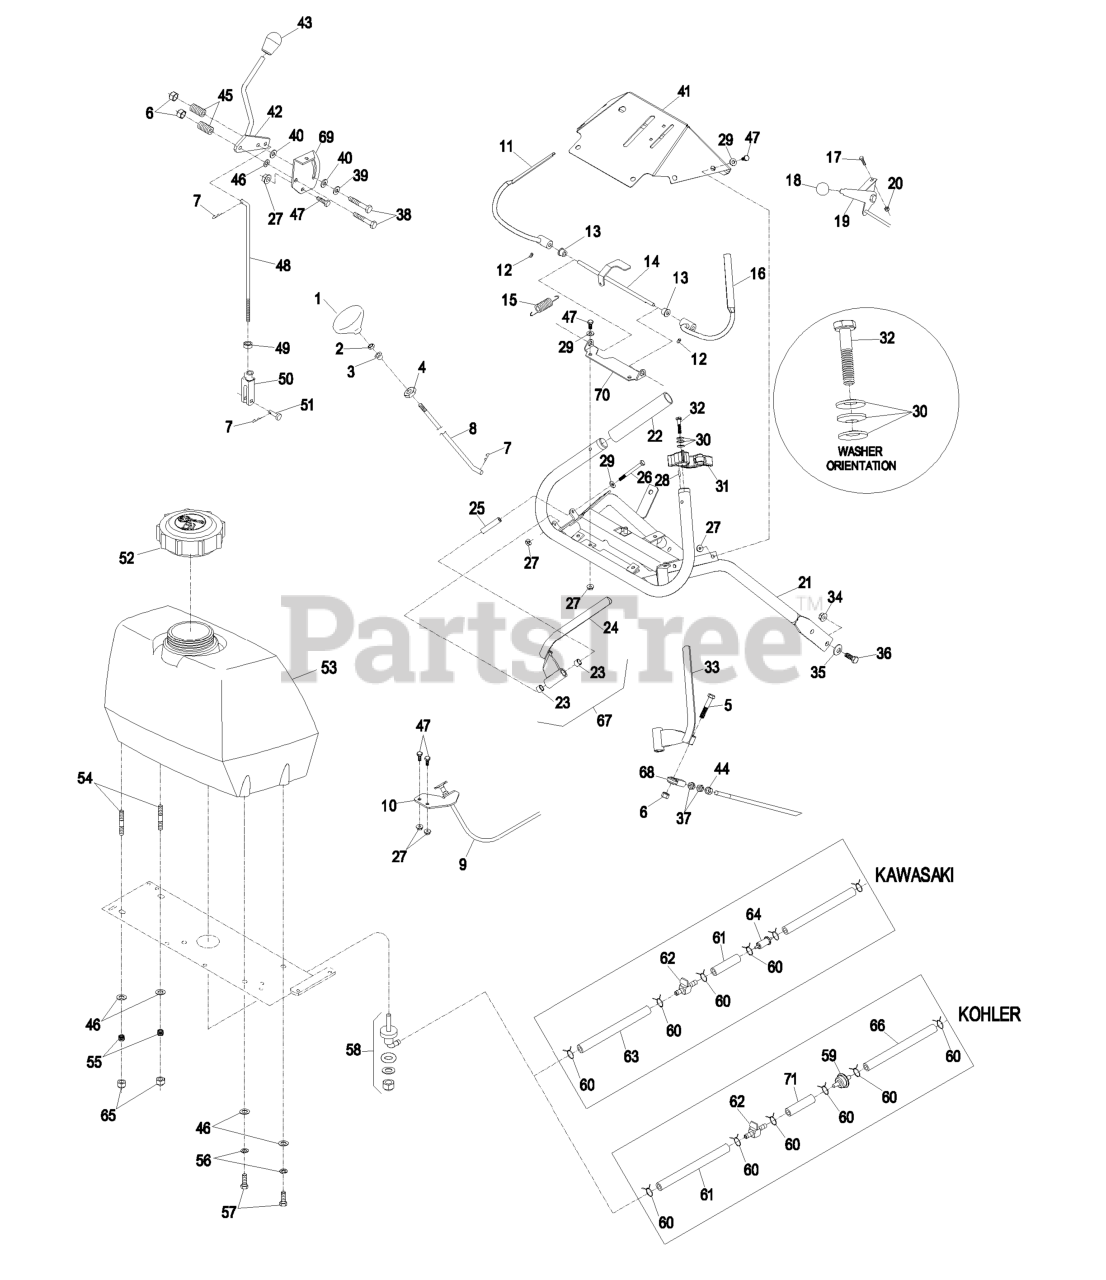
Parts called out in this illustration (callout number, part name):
1	KNOB-PUSH / PULL
2	NUT-JAM
3	BEARING-NYLON
4	NUT-PUSH
5	SCREW-HH
6	NUT-LOCK, NI
7	PIN-COTTER
8	LINKAGE,BLADE PUSH/PULL
9	CABLE-CHOKE
10	BRACKET-CABLE, CHOKE
12	SCREW-SET
13	BUSHING-NYLON
14	WLD,OPC LEVER AXLE
15	SPRING-EXTENSION
17	BOLT-CARR
18	KNOB-BALL
19	CONTROL,THROTTLE
20	NUT-LOCK, NI
21	WLD,VH ECS HANDLE
22	GRIP-BAR, HANDLE
23	BUSHING-SLEEVE
25	BUSHING-LEVER, DRIVE
26	SCREW-HH
27	NUT-HF
29	WASHER-FLAT
30	WASHER-SPRING
31	ASM,LATCH RH THUMB
32	SCREW-HH
34	NUT-HHF, WHIZ
35	WASHER-BELLEVILLE
36	SCREW-HH
37	NUT-HJ
38	SCREW-HH
39	WASHER-FRICTION
40	WASHER-FRICTION
43	KNOB, FE.LCKG. BLACK
44	NUT-HEX
45	SPRING-COMPRESSION
46	WASHER-PLAIN
47	SCREW-HH
48	ROD-CONTROL, SPEED
49	NUT-JAM
50	YOKE-ADJUSTABLE
51	PIN-CLEVIS
53	ASM,FUEL TANK W/B
54	STUD
55	SPRING-TANK, FUEL
56	WASHER-LOCK
57	SCREW-HH
58	FITTING-FUEL, BULKHEAD
61	HOSE-FUEL
62	VALVE-FUEL
63	HOSE-FUEL
64	Kawasaki Pn 41019-1055 Filter W/6" Fuel Line
65	NUT-LOCK, NI
66	HOSE-LINE, FUEL
67	DRIVE LEVER-ASM, RH
68	JOINT-BALL, END
69	BRACKET,SHIFTER SLIDE (PL
70	BRACKET,OPC AXLE
71	HOSE-LINE, FUEL
